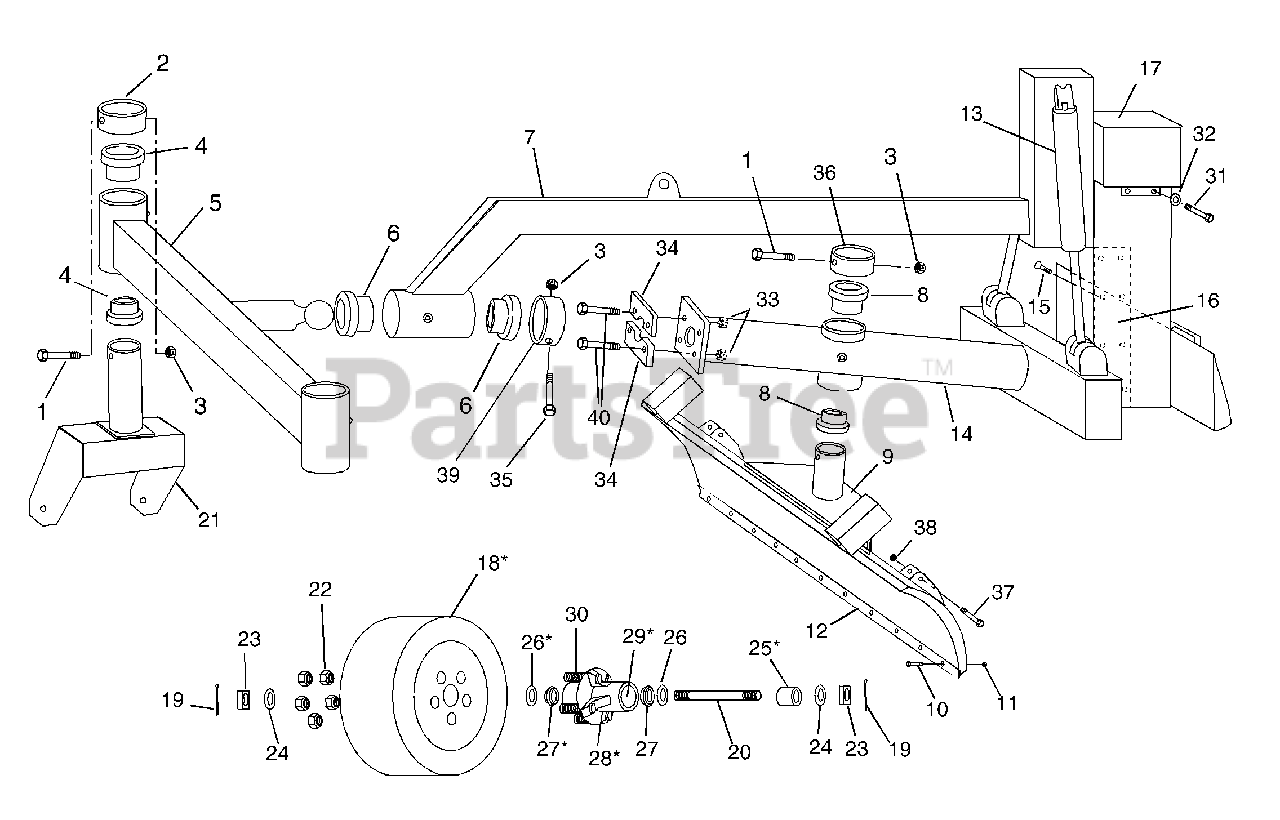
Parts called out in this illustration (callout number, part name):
1	Bolt .44-14 x 4 Grade 5
2	Retainer Collar
3	Nut-Lk-Ctr .44-14
4	Wheel Pivot Bushing
5	Front Beam
6	Beam Pivot Bushing
7	Main Frame
8	Blade Pivot Bushing
9	Blade Assembly
10	Plow Bolt .50-13 x 1.50
11	Lk-Ctr Nut .50-13
12	Cutting Blade
13	Cylinders
14	Torsion Beam
15	Flathead Screw 5/16-18 x .625
16	Plastic Tube Guide
17	Valve Cover
18	Tire, Hub, and Wheel Assembly
19	Cotter Pin .125 x 2.00
20	Axle Shaft 1"
21	Fork Assembly
23	Nut-Sl 1.0-14
24	Washer-Fl-Stl 1.062 x 2 x .134
25	Spacer 1.250 x 1.00 x .62
26	Oil Seal
27	Bearing Cone
29	Bearing Race
30	Mounting Bolt
31	Screw, Tap .25-20 x .50
32	Washer-Fl-Stl .281 x .62 x .065
33	Nut-Lk-Ctr .62-11
34	Pivot Ball Plate, Half
35	Bolt-Hex .44-14 x 5 Grade 5
36	Blade Collar
37	Bolt-Hex .38-16 x 3 Grade 5
38	Nut-Lk-Ctr .38-16
39	Collar, Retainer
40	Bolt-Hex .44-14 x 5 Grade 5
